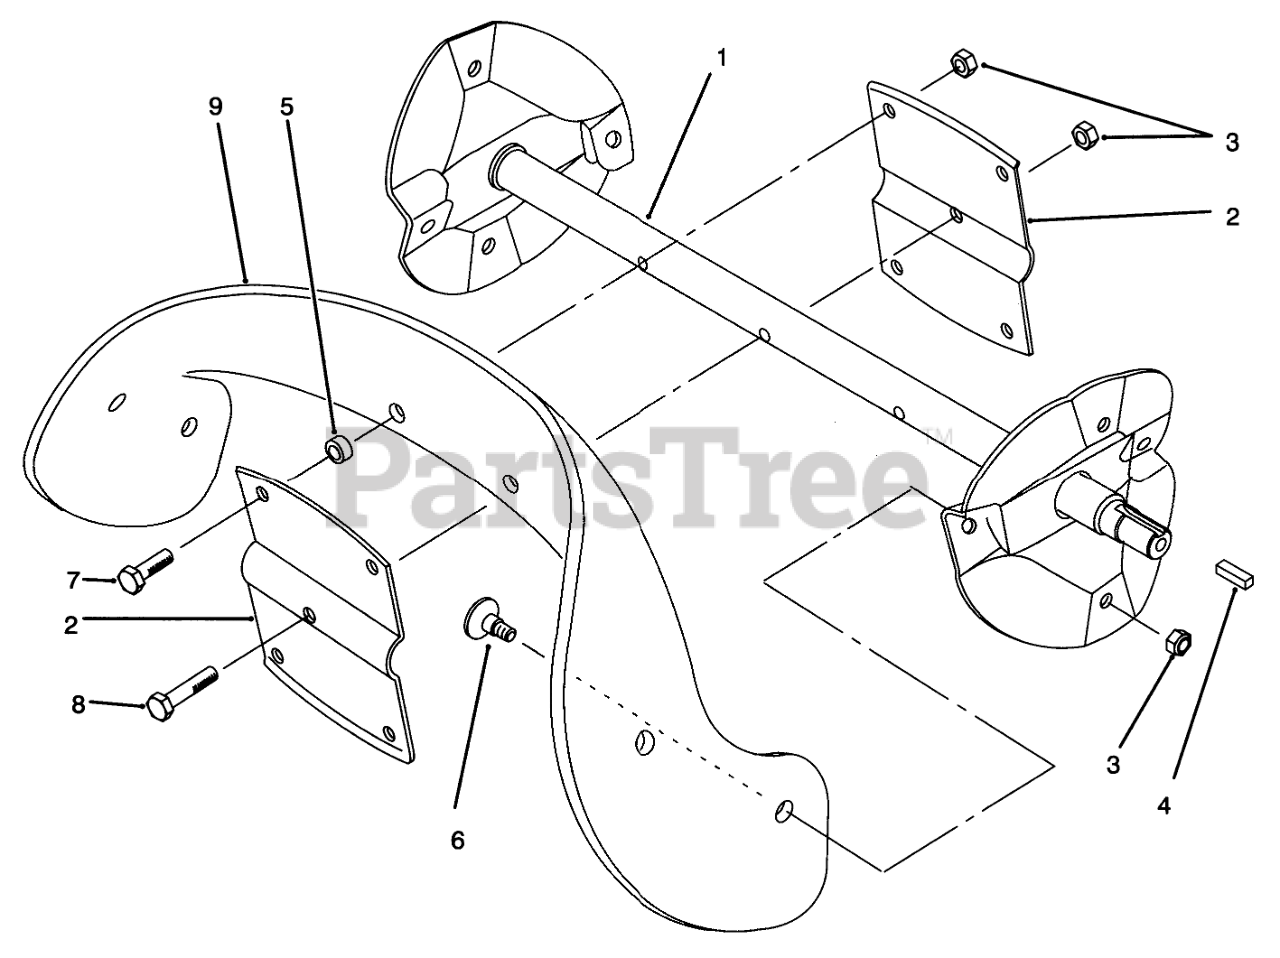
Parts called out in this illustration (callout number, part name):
1	Wa-Rotor
2	Rotor
3	NUT-LOCK, NI
4	KEY-SQUARE
5	SPACER-BLADE, ROTOR
6	SCREW
7	SCREW-HH
8	SCREW-HH
9	Blade-Rotor
